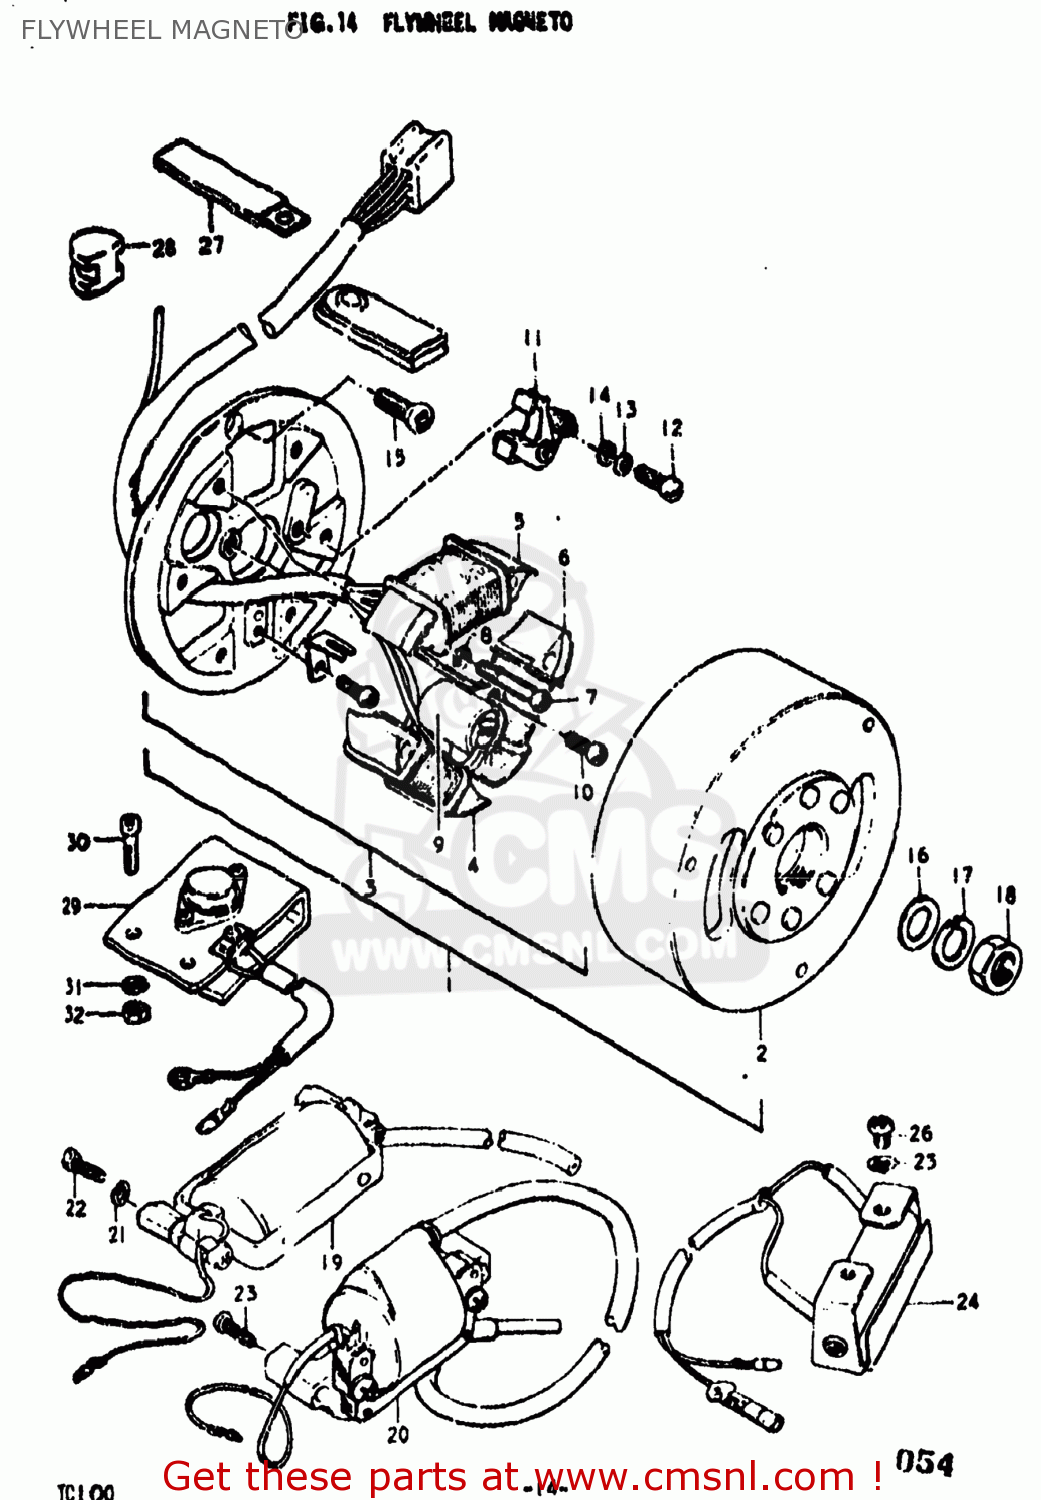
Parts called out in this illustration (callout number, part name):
1	MAGNETO ASSEMBLY
2	ROTOR ASSEMBLY
3	STATOR ASSEMBLY
4	COIL,LIGHTING
5	COIL
6	COIL
7	SCREW
8	LOCK WASHER
9	CONDENSER
10	SCREW
11	POINT ASSEMBLY,CONTACT
12	.SCREW
13	LOCK WASHER
14	WASHER
